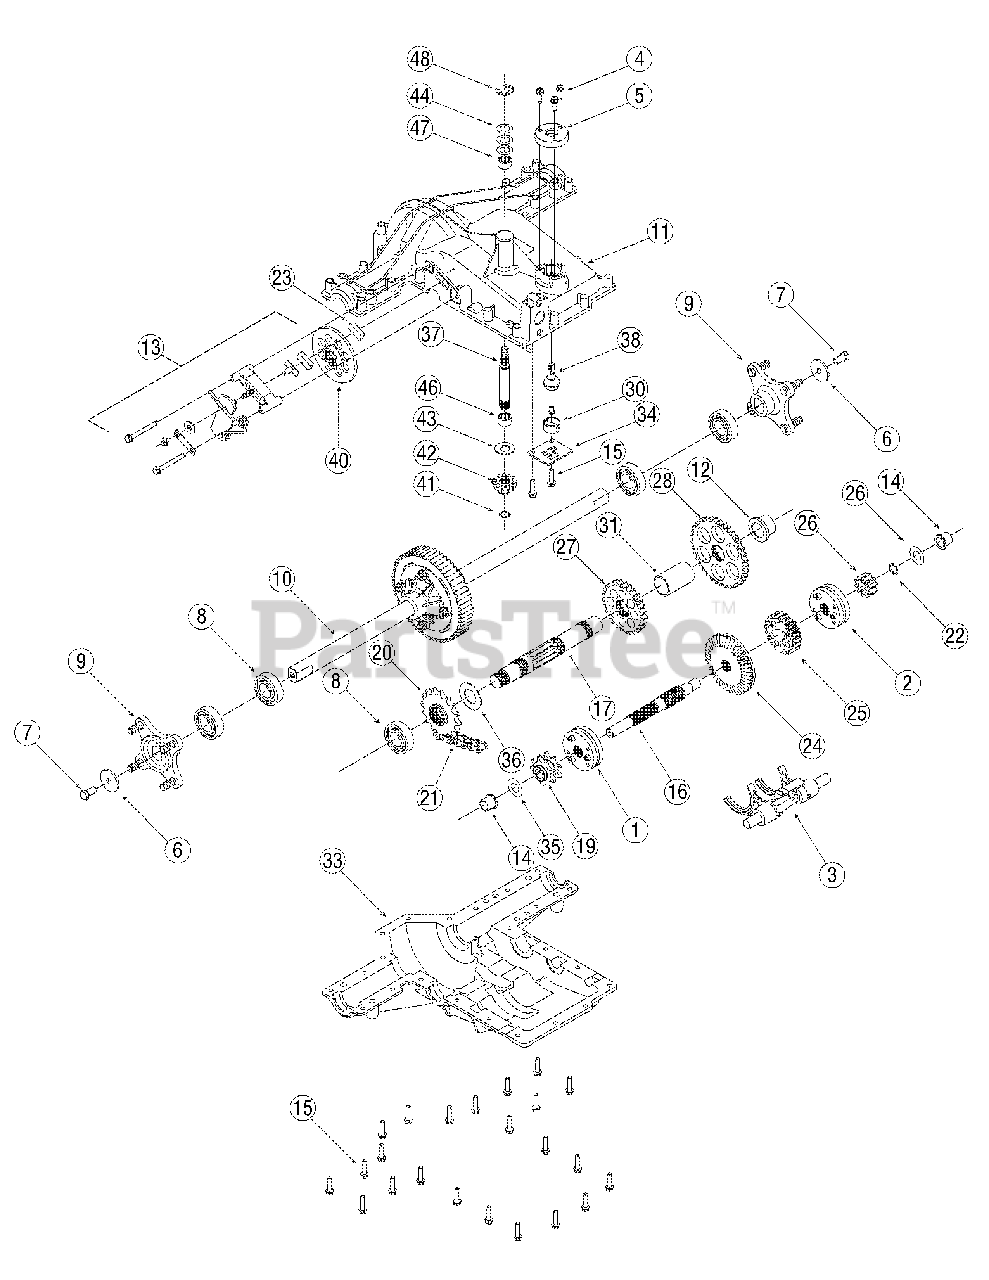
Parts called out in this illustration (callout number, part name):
1	Reverse Collar Assembly
2	Hi-Lo Collar Assembly
3	Shift Fork Assembly
4	Self-tapping Screw, 1/4-20 x.75
5	Shift Cover
6	Flat Washer
7	Lock bolt 3/8-16 x 0.75
8	Ball Bearing
9	Wheel Hub Assembly, DD
10	Differential Axle Assembly
11	Upper Housing
12	Flanged Bearing
13	Brake Assembly
14	Flanged Bearing
15	Screw 1/4-20 x 1.0
16	Drive Shaft
17	Output Shaft
19	9-tooth Sprocket
20	16-tooth Sprocket
21	22-link Chain,.625
22	External Snap Ring
23	Brake Pad
24	41-tooth Bevel Gear
25	20-tooth Spur Gear
26	10-tooth Spur Gear
27	27-tooth Spur Gear
28	37-tooth Spur Gear
30	Shifter Insert
31	Shifter Cover
33	Lower Housing
34	Lockout Plate
35	Flat Washer, 5/8 x 1.0
36	Flat Washer, 1.01 x 1.86 x.060
37	Input Shaft
38	Shift Lever
40	Disc Brake
41	Retaining Ring,.56
42	13-tooth Bevel Gear
43	Flat Washer
44	Flat Washer, 5/8 x 1.0 x.030
44	Flat Washer, 5/8 x 1.0 x.040
44	Flat Washer, 5/8 x 1.0 x.020
46	Needle Bearing
47	Needle Bearing
48	E-ring, .75
